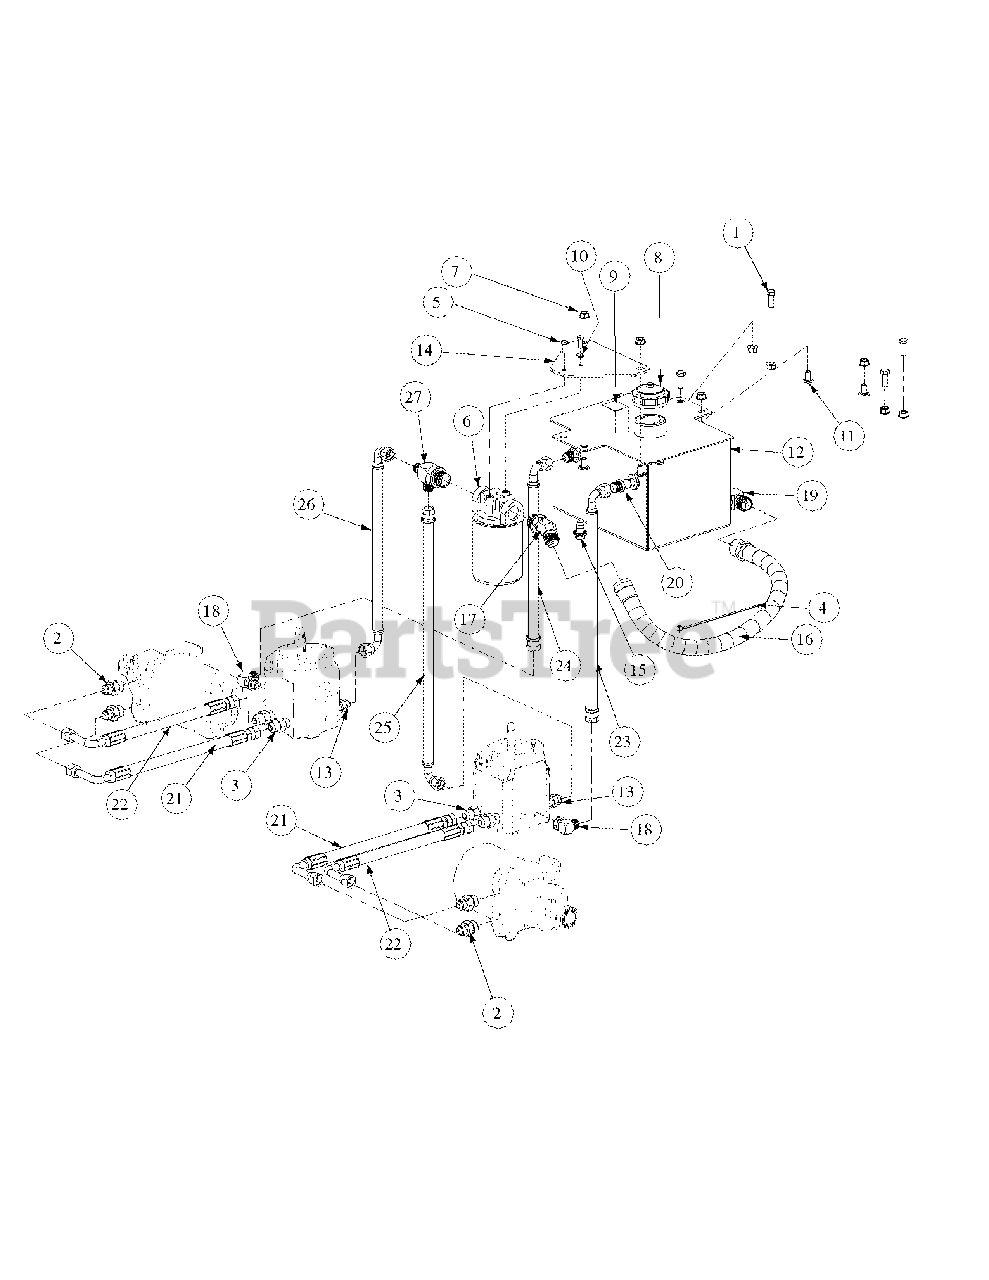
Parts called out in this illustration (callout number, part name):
1	Hex Cap Screw, 3/8-16, 1
2	Fitting 1/2 x 3/4 - O Ring
3	Fitting 1/2 x 1/2 - O Ring to Flare
4	Cable Tie, 3/16 x .05 x 7.4
5	Hex Cap Screw, 1/4-20, .75
6	Filter Head 3/4
7	Hex Nut Flange Lock, 3/8-16
8	Cap, Hydro Oil Tank
9	Decal Oil Only 20W50
10	Lock Washer, 1/4
11	Carriage Bolt, 3/8-16 x .75 LG.
12	Hydraulic Tank Assembly
13	Fitting Connector, 1/2 x 3/8
14	Oil Filter Mounting Plate
15	Oil Pan Drain Plug w/ Seal
16	Tank to Filter Hose Assembly
17	Fitting, 3/4 x3/4 x 45 degree
18	Elbow Fitting, 3/8 O-ring, 1/2 Flare
19	Fitting Elbow, 1/2 x 1/2
20	Fitting, 3/8 NPT, 1/2 Flare
21	Long Pressure Hose Assembly
22	Short Pressure Hose Assembly
23	17.75" Return Hose Assembly, RH
24	14.25" Return Hose Assembly, LH
25	21.25" Supply Hose Assembly, RH
26	15.50" Supply Hose Assembly, LH
27	Tee Fitting, 3/4 x 1/2 x 1/2
